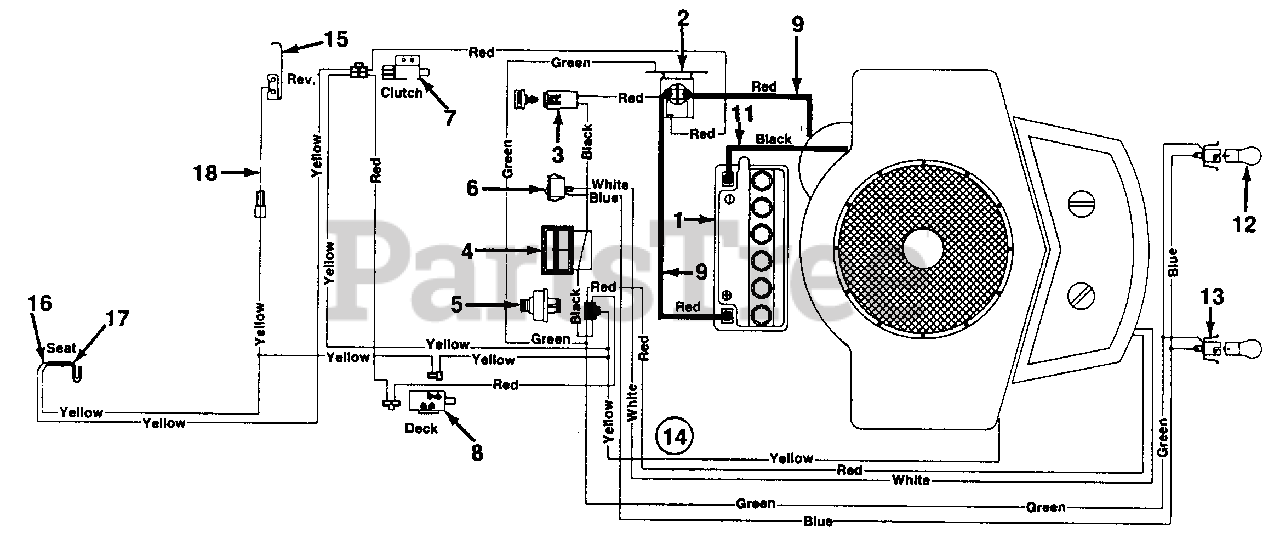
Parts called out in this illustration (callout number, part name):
1	Battery
2	Solenoid
3	Fuse 7.5 Amp
4	Ammeter
5	Ignition Switch
6	Light Switch
7	Safety Switch
8	Safety Switch
9	Electric Wire 14" Lg.
11	Ground Wire 7.5" Lg.
12	Lamp
13	Socket
14	Wire Harness
15	Spring Switch
16	Spring Switch
17	Spring Switch
18	Ext. Wire
